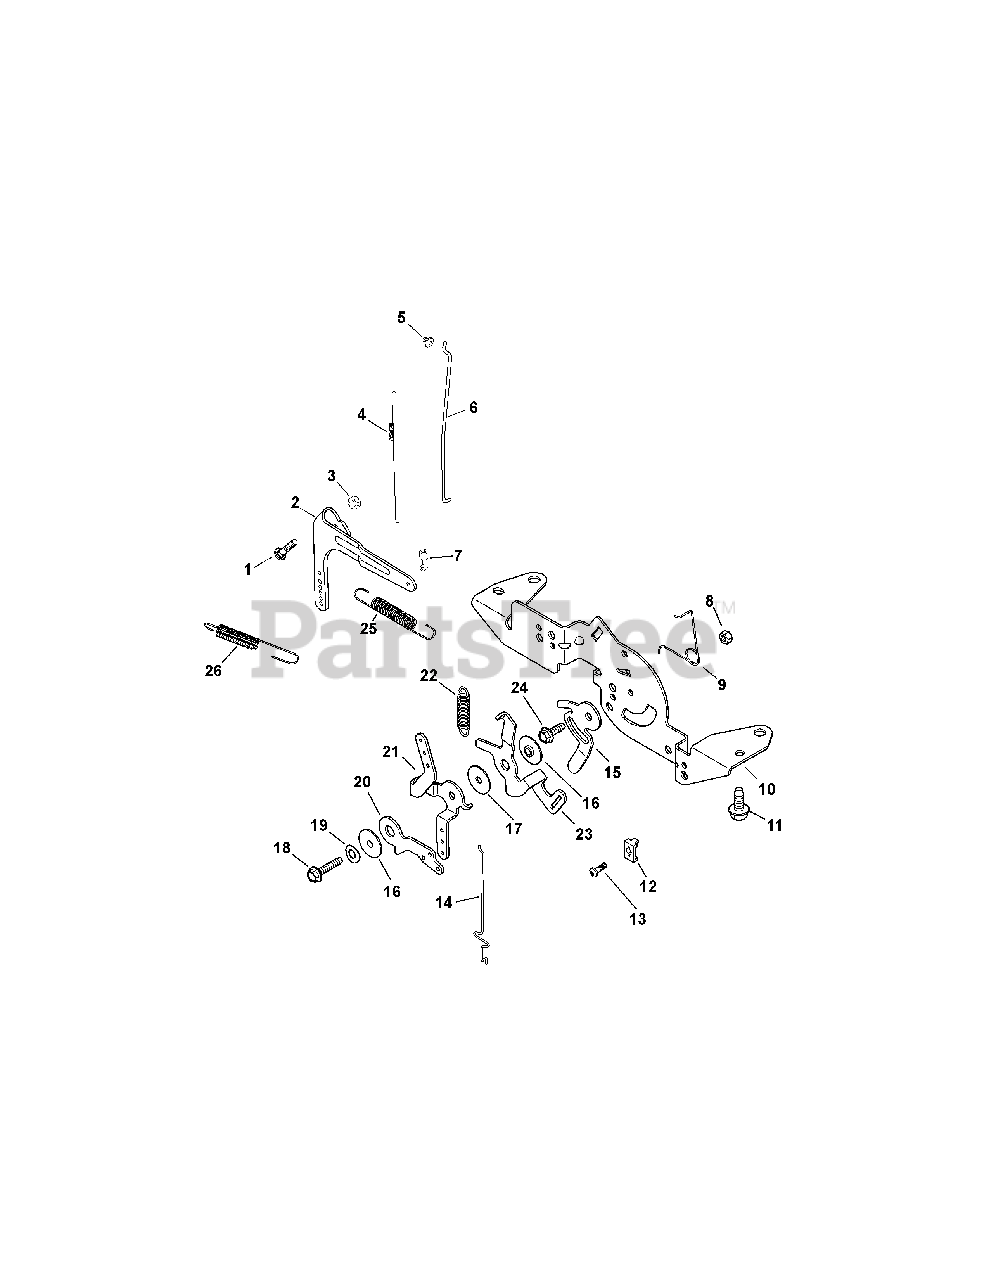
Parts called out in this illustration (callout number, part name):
1	Rd. Hd. Sq. Neck Bolt, M6 x 1.0 x 25
2	Governor Lever
3	Flg. Nut, M6 x 1.0
4	Linkage Spring
5	Linkage Retaining Bushing
6	Throttle Linkage
7	Throttle Linkage Bushing
8	Lock Nut, M5 x .8
9	Choke Return Spring
10	Control Bracket
11	Flg. Thd. Frm. Screw, M6 x 1.0 x 16
12	Cable Clamp
13	Lbd. Thd. Frm. Screw, M5 x 0.8 x 16
14	Choke Linkage
15	Speed Setting Lever
16	Control Assembly Spacer
17	Flat Washer, 5.5MM
18	Thd. Frm. Screw, M5 x 0.8 x 25MM
19	Spring Washer, 1/4"
20	Choke Lever
21	Speed Control Lever
22	Speed Control Spring
23	Governor Spring Lever
24	Flg. Thd. Frm. Screw, M5 x 0.8 x 16
25	Governor Spring
26	Governor Spring
